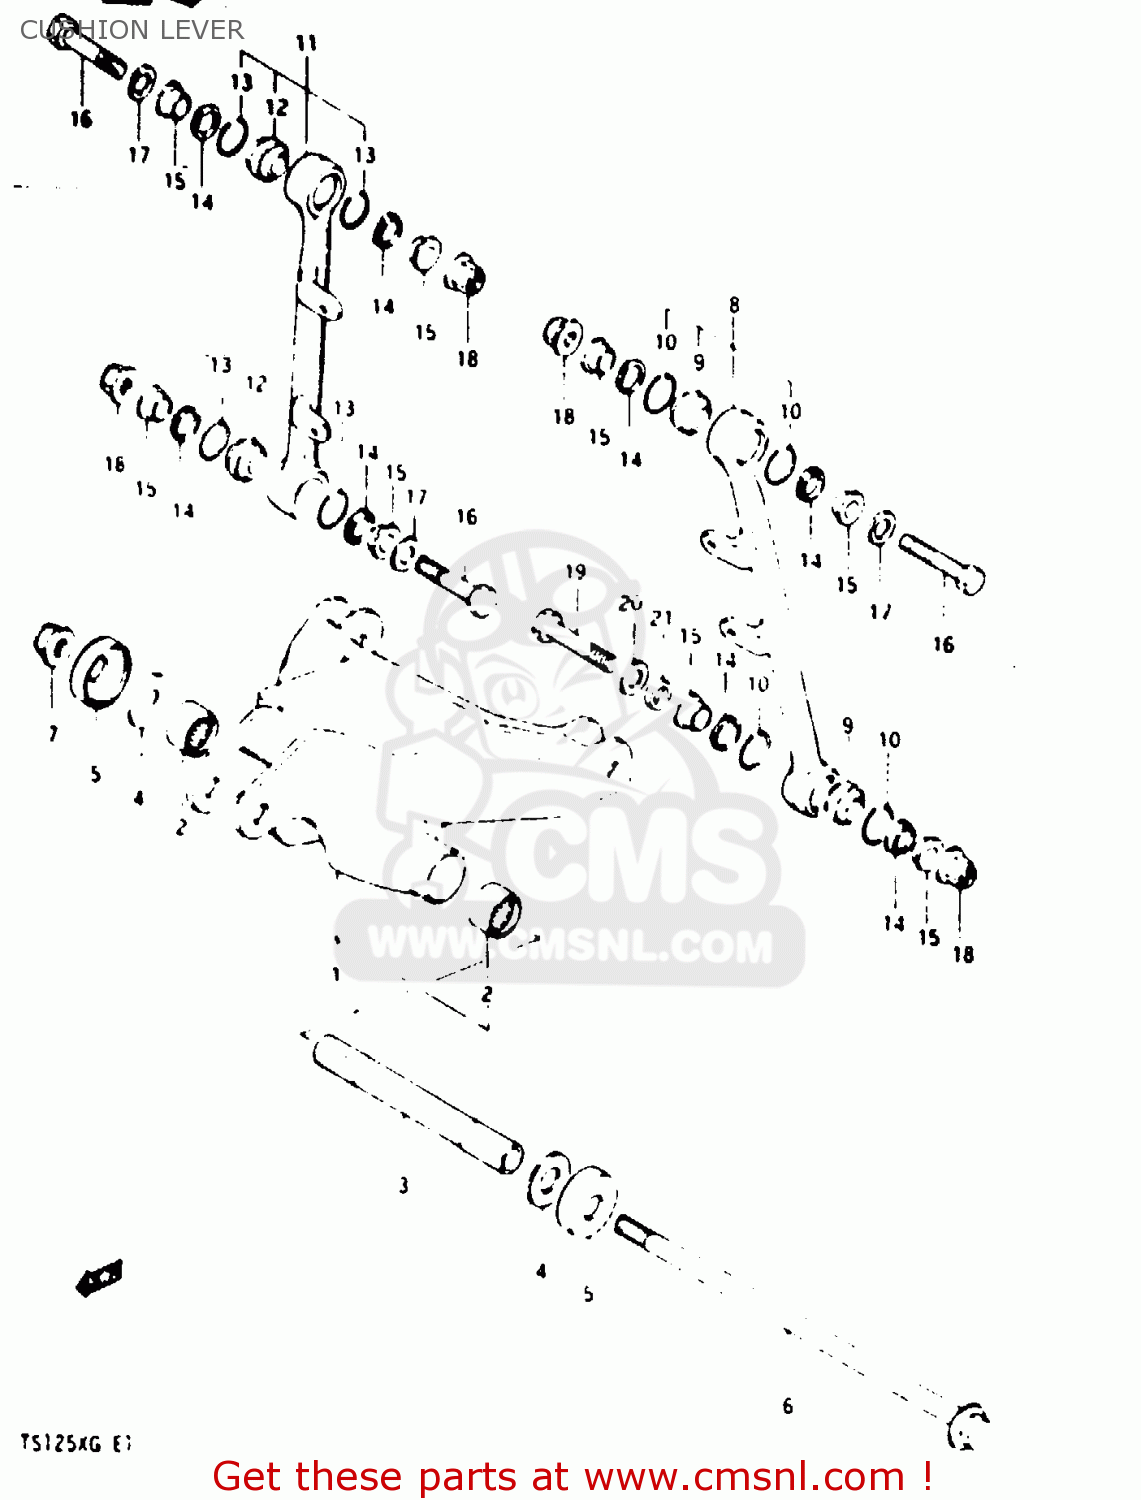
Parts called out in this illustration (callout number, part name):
1	LEVER SET, CUSHION
2	ROLLER BEARING (17X24X25)
3	SPACER
4	WASHER
5	COVER,RR SWGARM DUST SEAL
6	SHAFT
7	NUT 12MM
8	ROD SET, LEVER LH
9	BEARING(8X18X11)
10	RING, STOPPER
11	ROD SET, LEVER RH
12	BEARING(8X18X11)
13	RING, STOPPER
14	DUST SEAL
15	SPACER
16	BOLT,REAR CUSHION ROD
17	WASHER
18	NUT
19	BOLT, LOWER LH
20	WASHER
21	SPACER(8.5X12X2.5)
